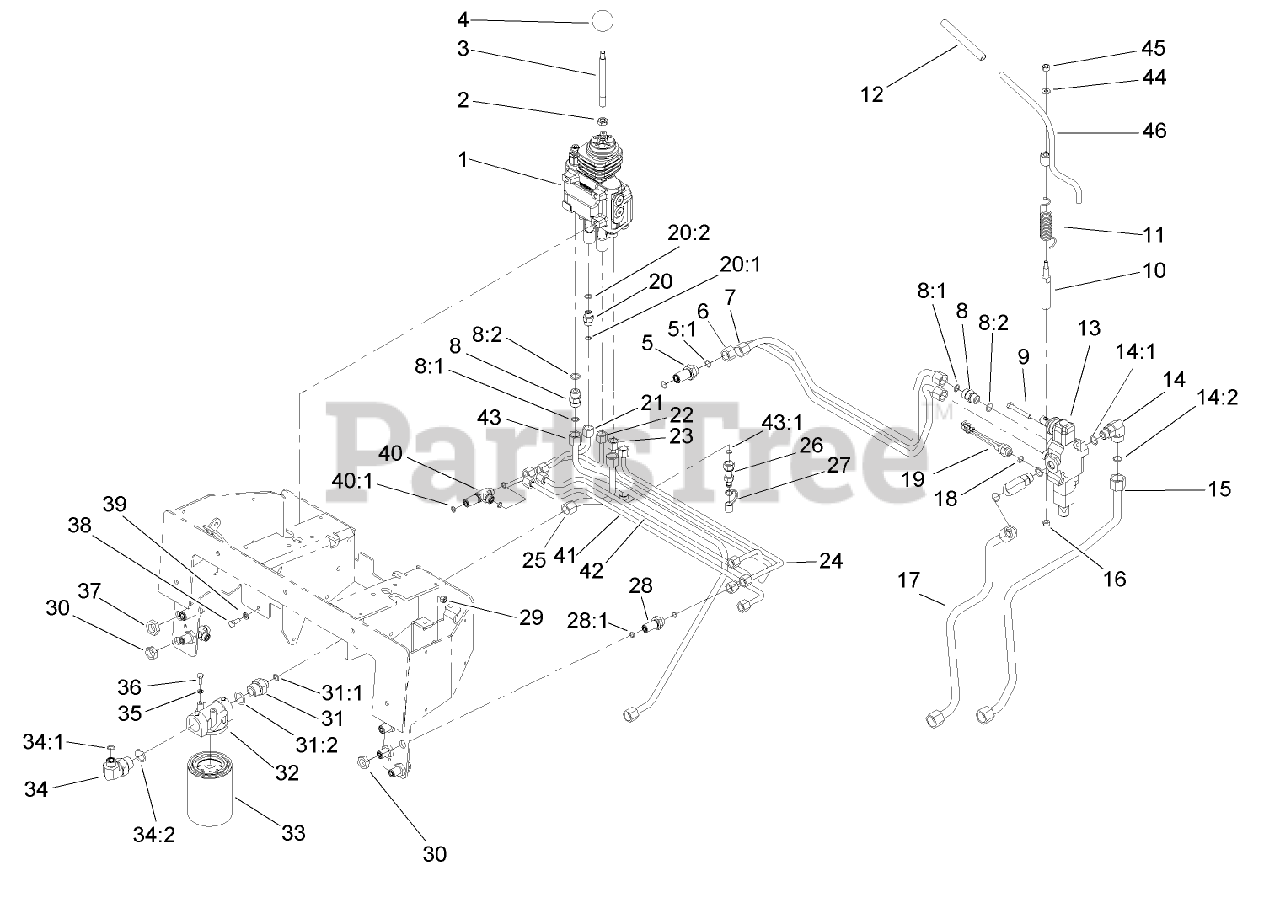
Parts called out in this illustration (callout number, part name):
1	2 SPOOL VALVE ASM
3	SHAFT-HANDLE, LOADER
5	FITTING-BULKHEAD
5:1	O-RING
6	TUBE-HYD
7	TUBE-HYD
8	FITTING-STRAIGHT
8:1	O-RING
8:2	O-RING
9	SCREW-HH
10	SPACER-HIFLO
11	SPRING-TORSION
12	CAP-ROD, TILT
13	1 SPOOL VALVE ASM
14	Fitting-Elbow, 90 DEG
14:1	O-RING
14:2	O-RING
15	TUBE-HYD
16	SCREW
17	TUBE-HYD
18	O-RING
19	SWITCH-BALL
20	FITTING-STRAIGHT
20:1	O-RING
20:2	O-RING
21	TUBE-HYD
22	TUBE-HYD
23	TUBE-HYD
24	TUBE-HYD
25	TUBE-HYD
26	NIPPLE-TEST
27	CAP-DUST
28	FITTING-STRAIGHT, BULKHEAD
28:1	O-RING
29	NUT-LOCK, NI
30	NUT-LOCK
31	FITTING-STR
31:1	O-RING
31:2	O-RING
32	HEAD-FILTER
33	FILTER-OIL
34	FITTING-HYD, 90 DEG
34:1	O-RING
34:2	O-RING
35	WASHER-LOCK
36	SCREW-HH
37	NUT-BULKHEAD
38	SCREW-HH
39	WASHER-LOCK
40	FITTING-TEE, BULKHEAD
40:1	O-RING
41	TUBE-HYD
42	TUBE-HYD
43	HYD TUBE ASM
43:1	O-RING
44	WASHER-FLAT
45	NUT-LOCK, NI
46	AUXILIARY LEVER ASM
